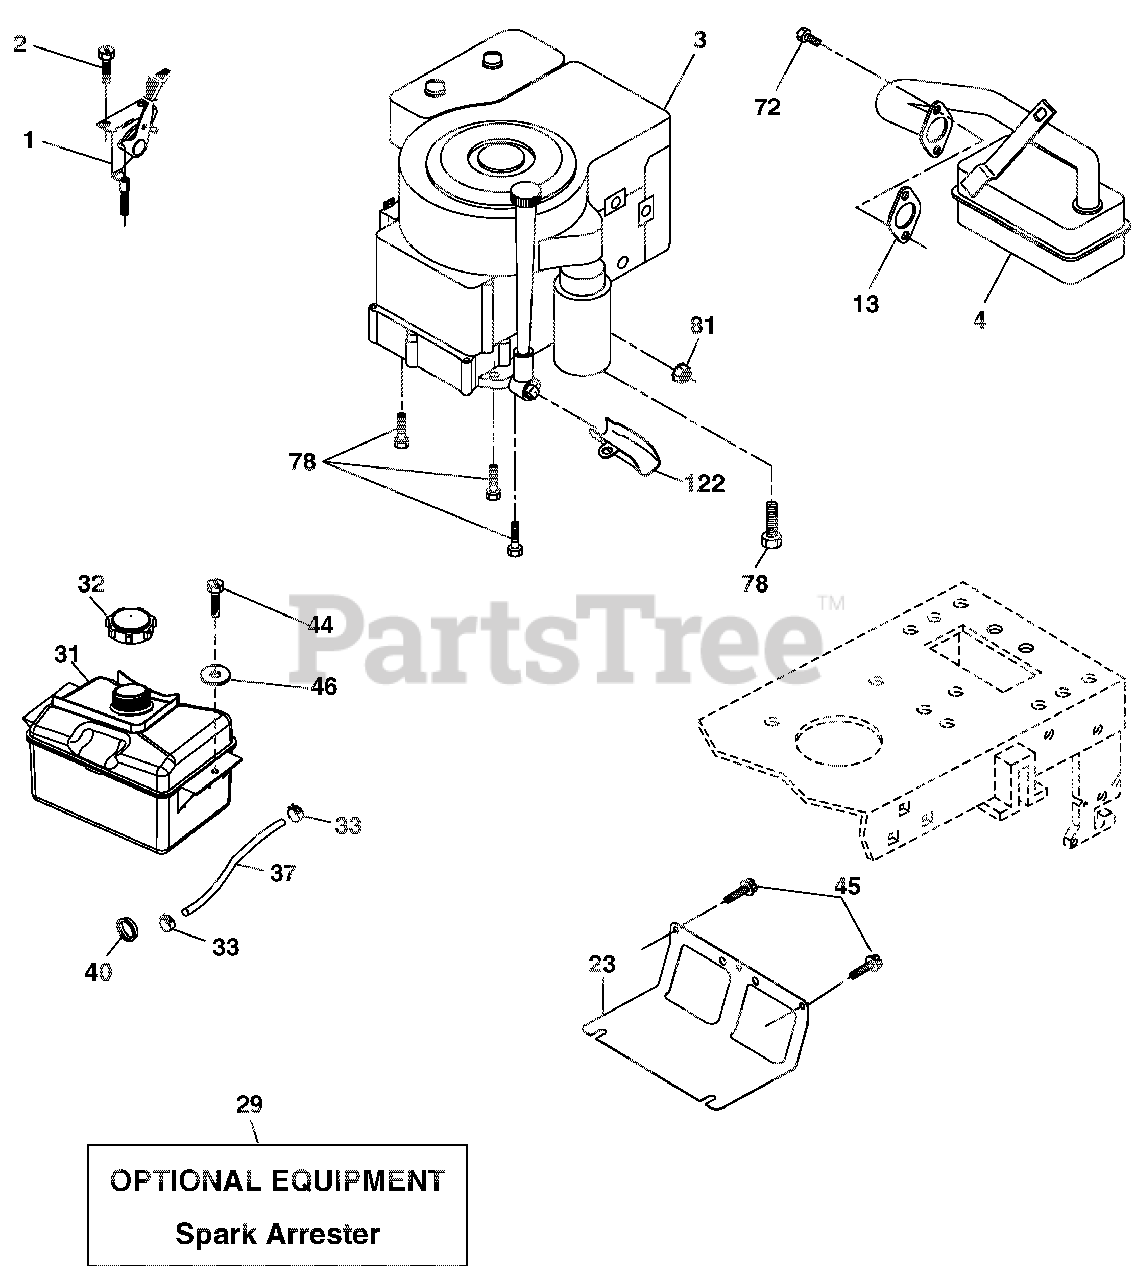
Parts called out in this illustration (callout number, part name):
1	Control Th/ch Flag
2	Screw 1/4-20 x 1/2
3	ENGINE, B&S 31C707-3346-G1(438207) (ORDER PARTS FROM ENGINE MANUFACTURER.)
4	Muffler Exhaust B&S
13	Gasket Eng 1 313 Id Tin Plated
23	Shield BRN/DBR Guard
29	KIT.SPARK ARRESTOR(392390 B&S)
31	TANK FUEL
32	CAP FUEL
33	CLAMP.HOSE.BLK.
37	LINE.FUEL.22"FRONT.EMIS.CA.LP
40	Bushing Snap Nyl Blk Fuel Line
44	SCREW.HEXWSH.THDROL.1/4-20X3/4
45	SCREW.HEXWSH THDR3/8-16X3/4.BL
46	WASHER.9/32 X 7/8 X 16GA.
72	SCREW.SOCKET HD.5/16-18 X .75
78	Screw 3/8-16 x <
81	Nut, Keps Hex 1/4-20 unc
122	Extension Drain Oil
